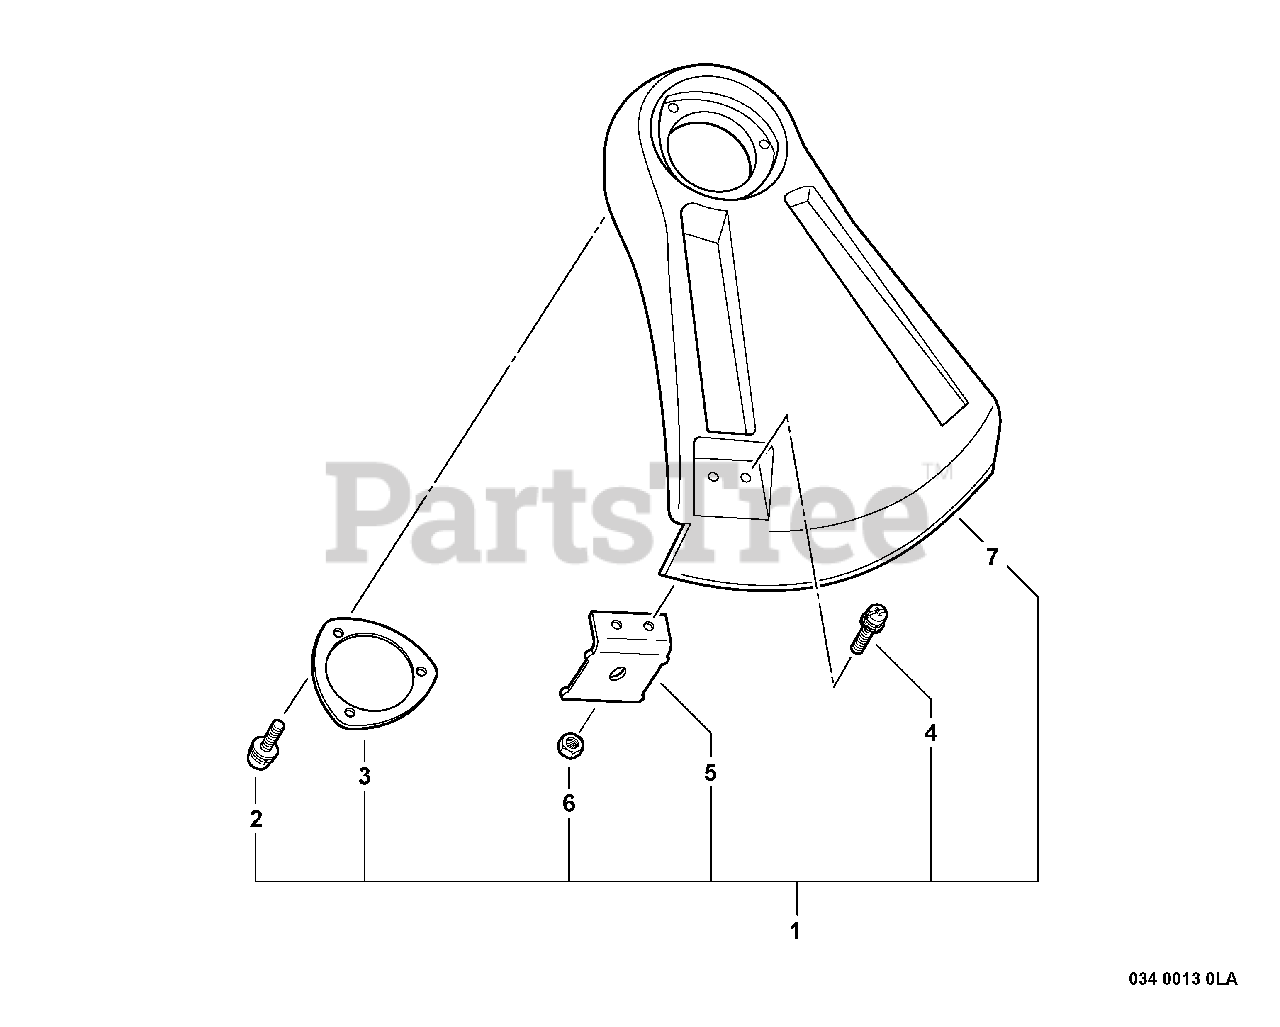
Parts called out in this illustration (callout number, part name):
1	DEBRIS SHIELD KIT - PLASTIC
2	SCREW - 5X16
3	PLATE, SHIELD
4	SCREW - 5X12
5	KNIFE, TRIMMER LINE
7	SHIELD, DEBRIS - PLASTIC
